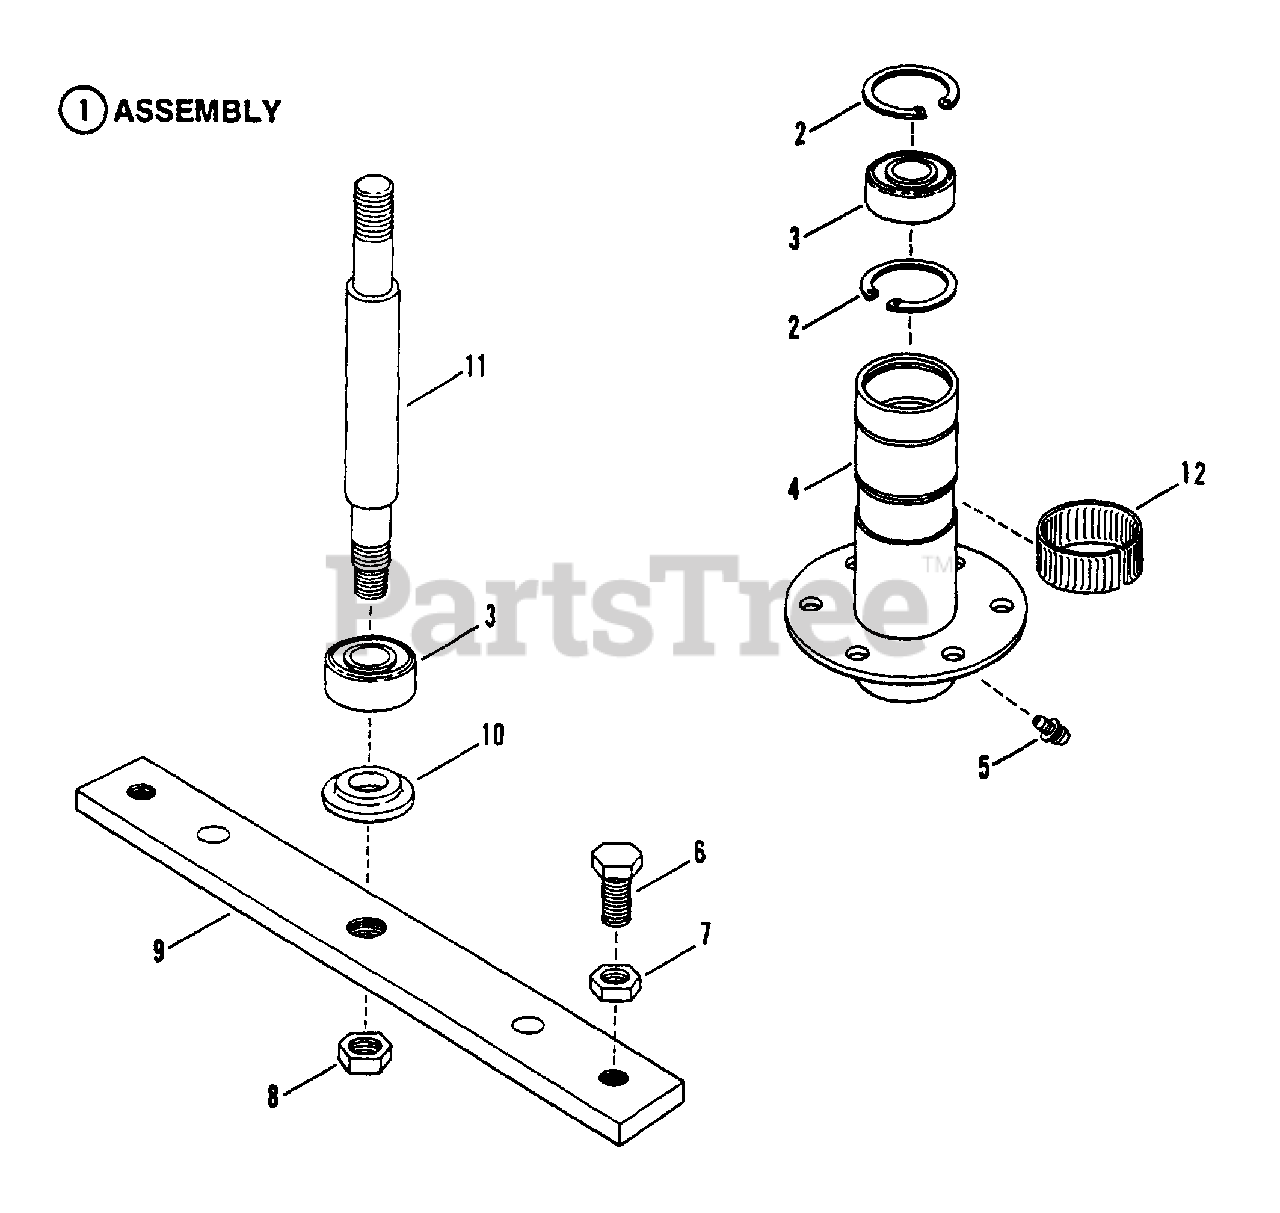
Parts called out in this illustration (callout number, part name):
1	ASSEMBLY, Spindle Housing, 30" Cutting Deck
2	RING, Retaining
3	BEARING, Spindle
4	HOUSING, Spindle
5	FITTING, Lube (Press fit for .187 hole-no ball)
6	SCREW, 1/2-20 x 1" Hex Head Cap, Gr. 5
7	NUT, 1/2-20 Hex Jam
8	NUT, 5/8-18 Hex Lock
9	HOLDER, Blade
10	WASHER, Spindle
11	SPINDLE, 7.54" Long
12	RING, Tolerance
